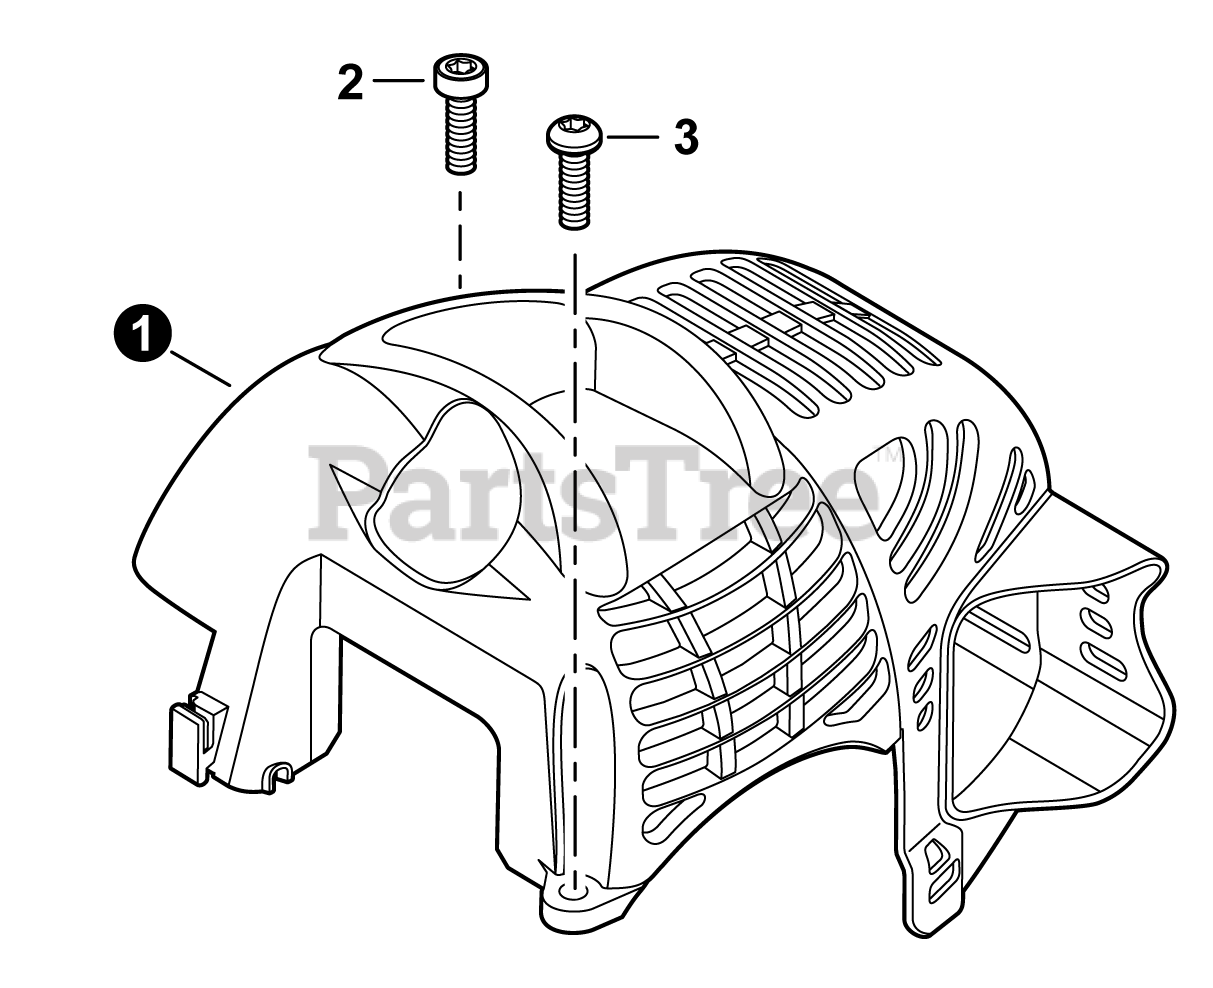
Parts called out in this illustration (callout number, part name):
1	COVER, ENGINE
2	BOLT, TORX 5x16
3	BOLT, TORX 5x16
